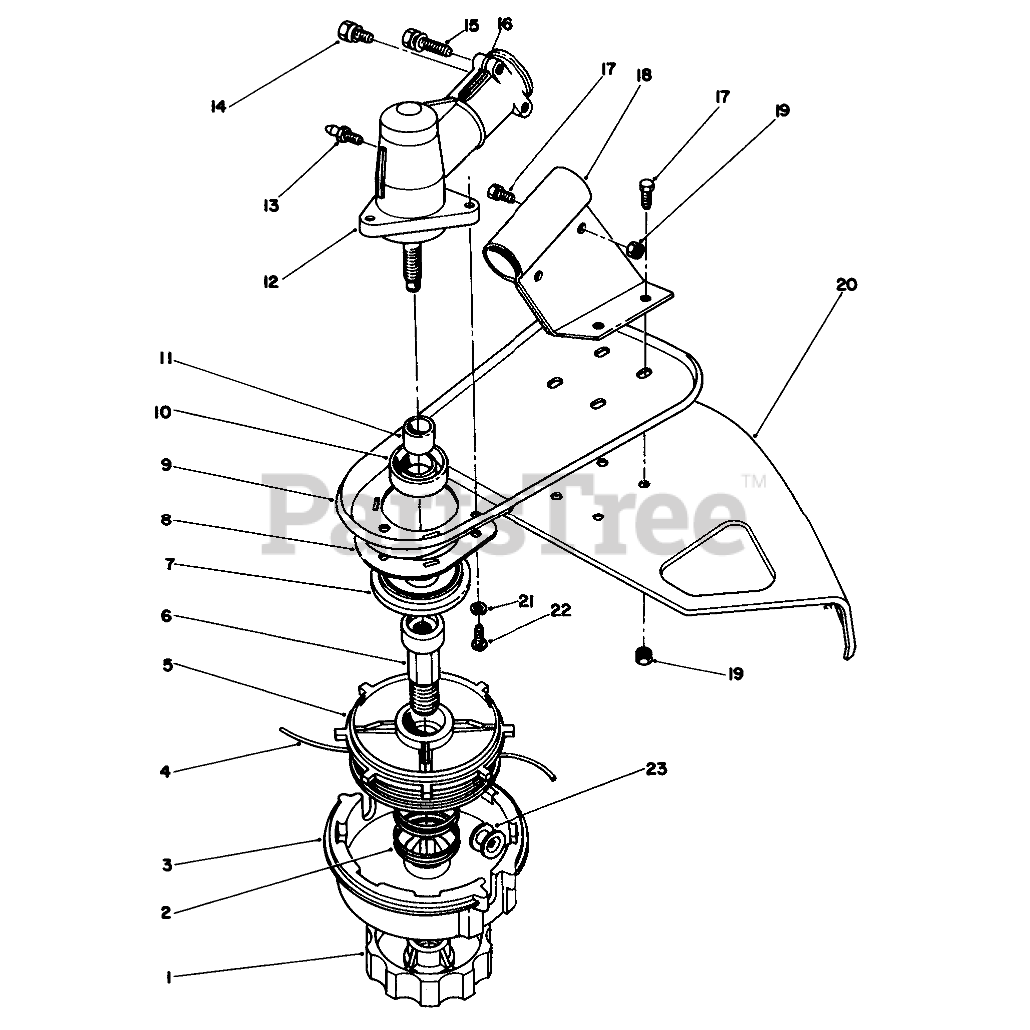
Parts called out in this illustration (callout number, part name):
1	LH KNOB(SERVICE ONLY)
2	SPRING (SERVICE)
3	SPOOL HSG (SERVICE ONLY
4	REPL LINE PKG
5	INNER SPOOL(SERV ONLY)
6	SHAFT (SERVICE ONLY)
7	DUST CAP F/W
8	GRASS WRAP GUARD
9	SHIELD SUPPORT R
10	OIL SEAL
11	SPLINED SLEEVE
12	Gear Box Assembly (Incl. Ref. #10, 11, & 13-15)
14	HHMS SCREW
15	HHMS SCREW
16	WASHER
17	SCREW-SHH
18	Bracket-Shield
19	NUT-LOCK, NI
20	GRASS SHIELD-STEEL
21	LOCKWASHER
22	SCREW
23	EYELET(SERVICE)
